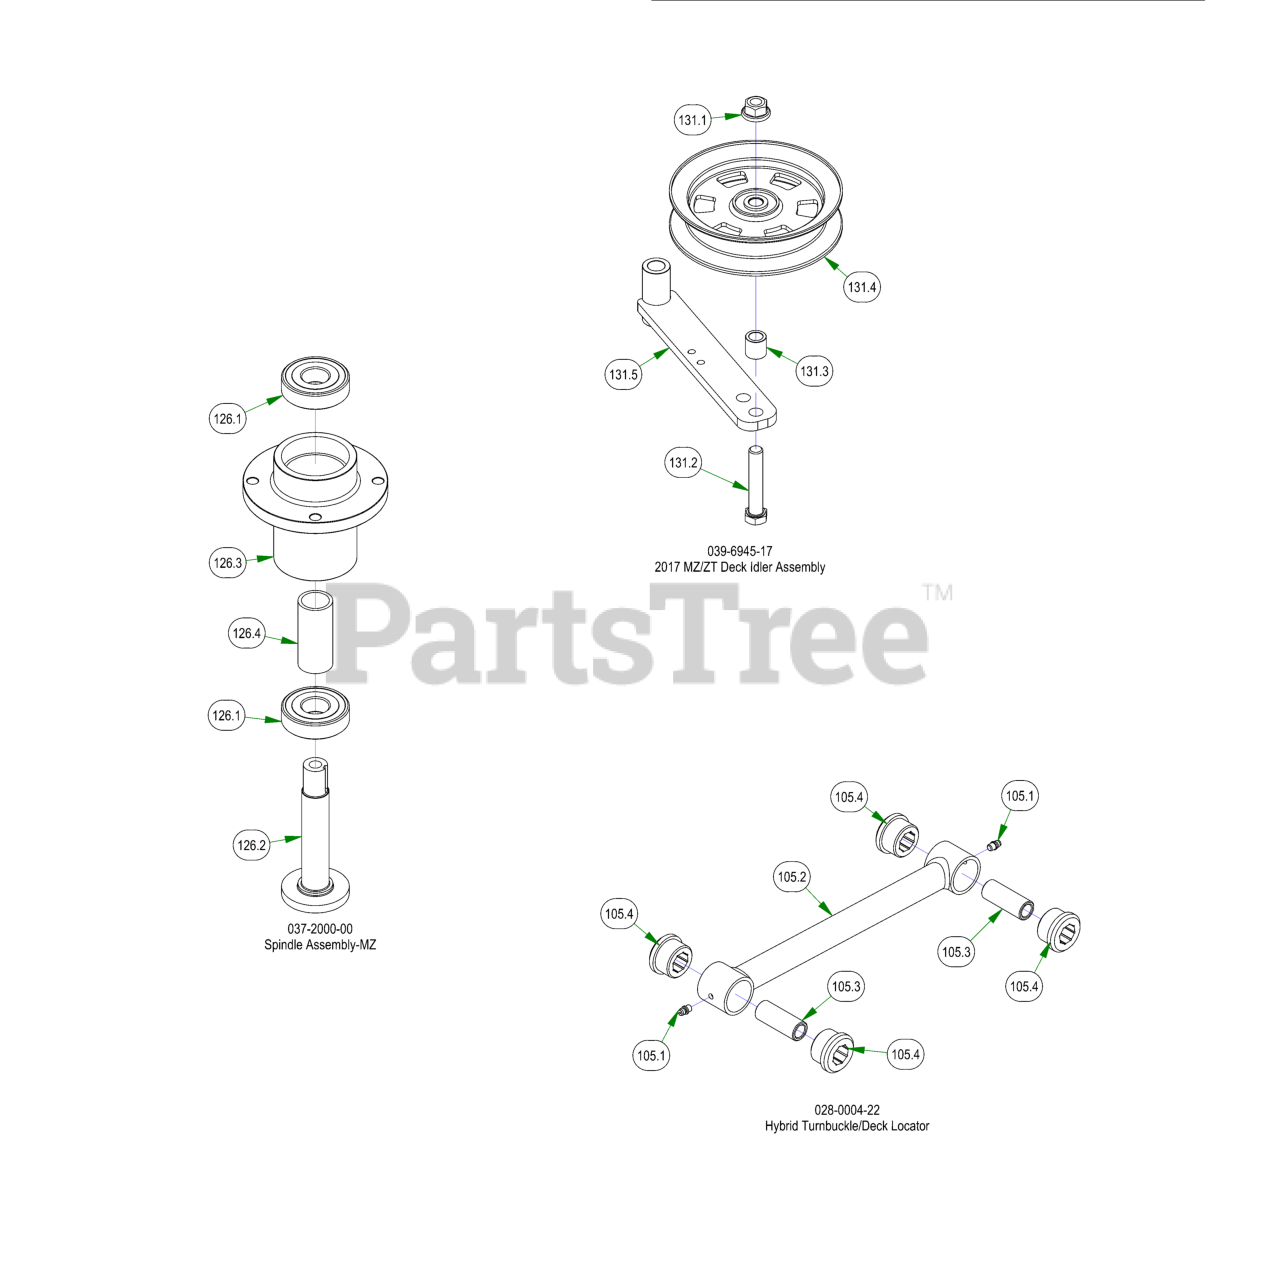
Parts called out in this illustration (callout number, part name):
105	Hybrid Turnbuckle/Deck Locator
105.1	1/4-28 Grease Fitting
105.2	2022 Isolator Turnbuckle Body
105.3	2018 Maverick Bushing Sleeve
105.4	2018 Maverick Bushing
126	Spindle Assembly-MZ
126.1	Spindle Bearing
126.2	Spindle Shaft
126.3	Spindle Housing
126.4	Spindle Spacer-Component
131	2017 MZ/ZT Deck Idler Assembly
131.1	1/2-13 NYLON INSERT FLANGE LOCKNUT ZINC
131.2	1/2-13 X 2-3/4 HEX CAP SCREW (GR.5) ZINC
131.3	Spacer 3/4 OD x 1/2 ID x 3\4 Length
131.4	5" Idler Pully
131.5	Deck Idler
